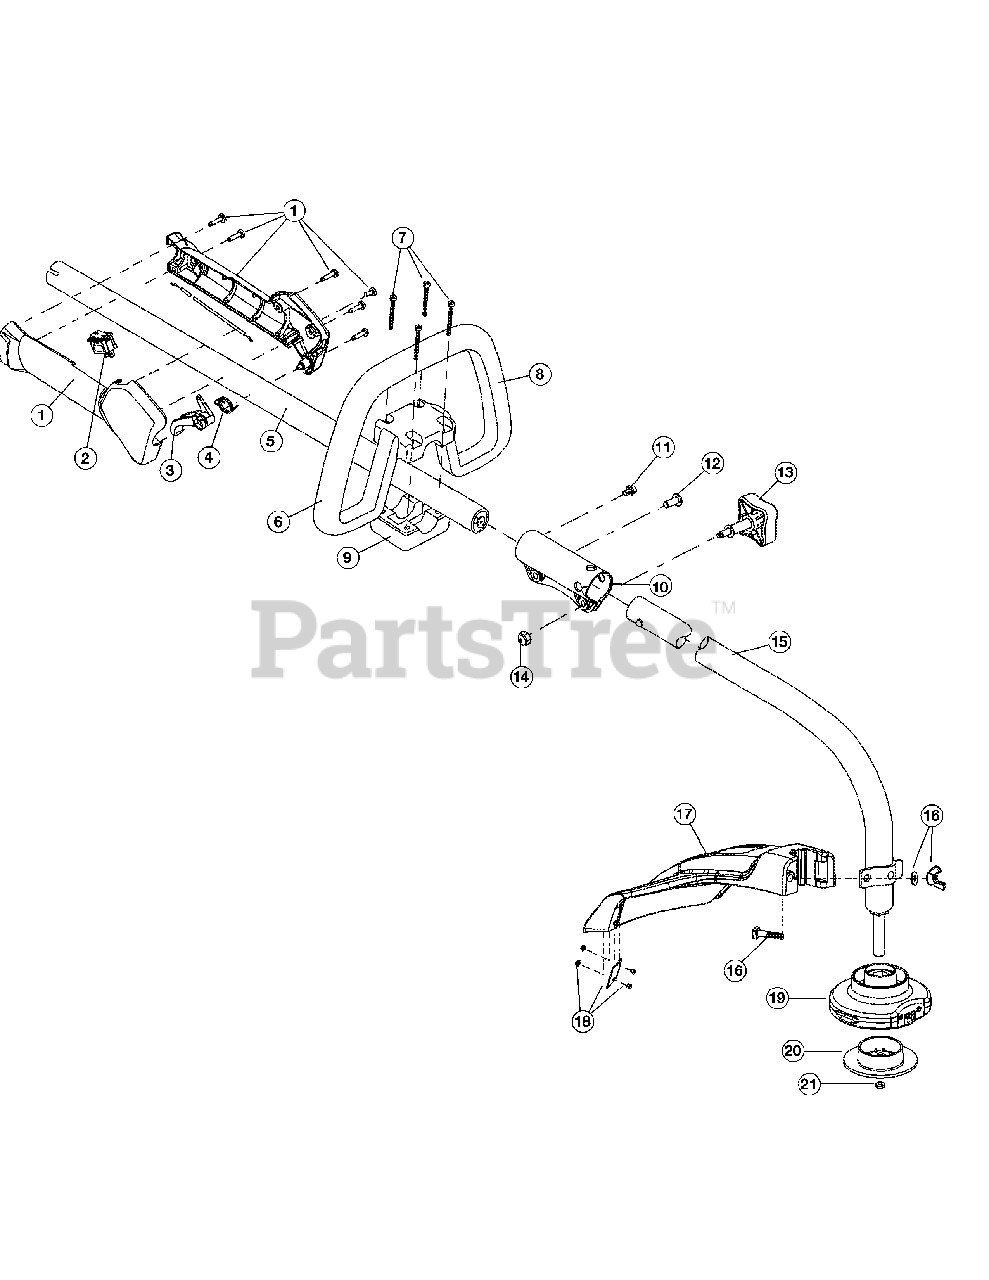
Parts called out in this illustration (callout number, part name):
1	Throttle Housing Assembly (Incl. 2-4)
3	Throttle Trigger
4	Throttle Trigger Spring
5	Upper Drive Shaft Housing Assembly
6	Deluxe D-Handle Assembly (Incl. 7-9)
8	Deluxe D-Handle
9	Deluxe D-Handle Base
10	Split Boom Coupler (Incl. 11-14)
13	Adjustment Knob
14	Knob Retaining Nut
15	Lower Drive Shaft Housing Assembly
16	Guard Mounting Hardware
17	Guard Assembly (Incl. 18)
18	Blade Assembly
19	Fixe Line Head Assembly (Incl. 20 & 21)
20	Glide Cap
21	Locknut
